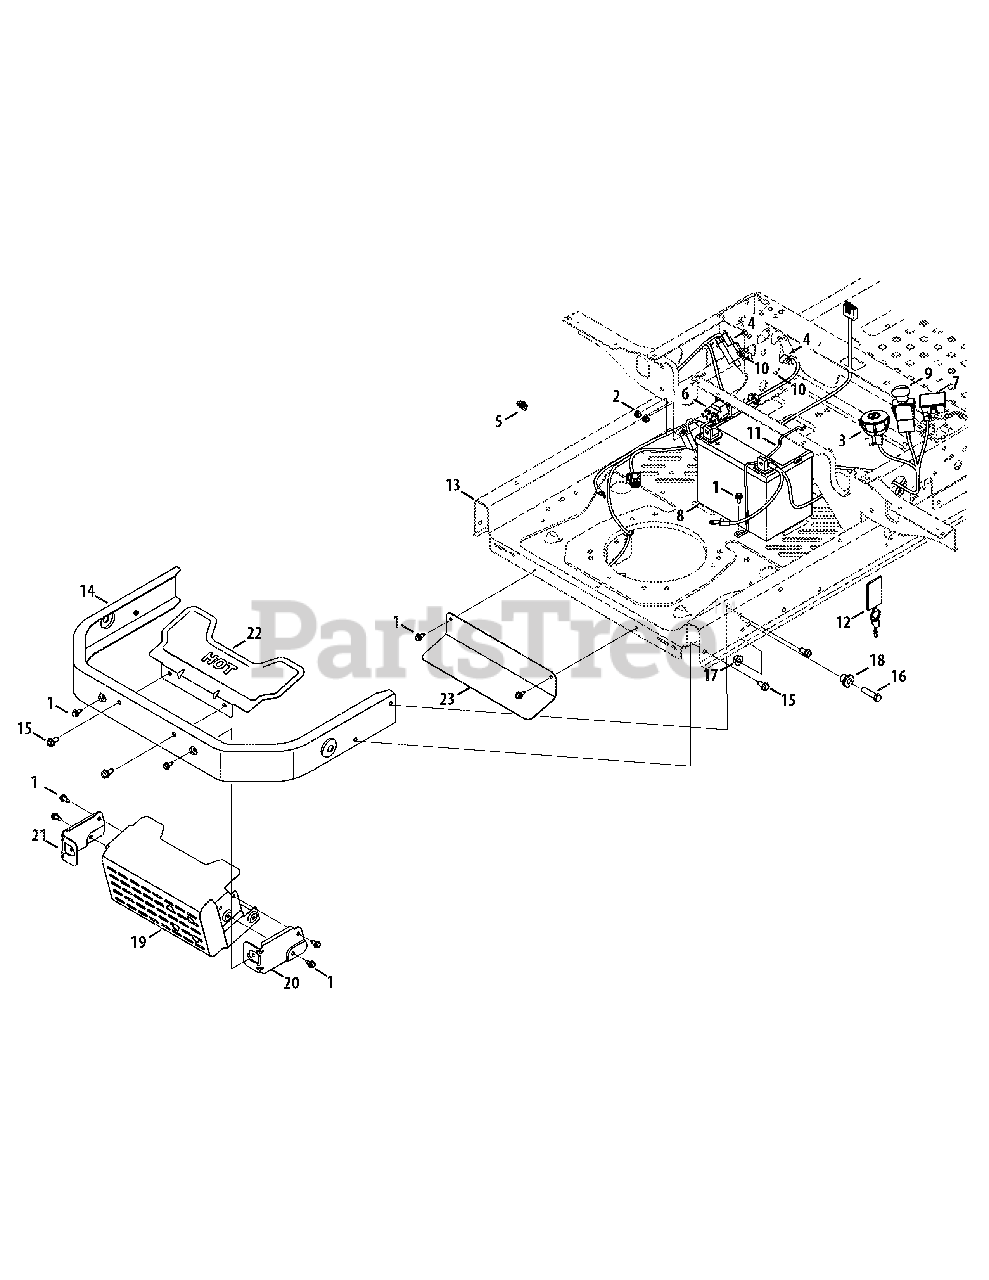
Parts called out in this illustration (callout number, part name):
1	Hex Washer Screw, 1/4-20 x .375
2	Flange Lock Nut, 1/4-20
3	Key Switch
4	Interlock Switch
5	Harness
6	Solenoid
7	Hour Meter/Service Minder
8	Battery
9	PTO Switch
10	Shoulder Screw
11	Battery Retainer
12	Key
13	Frame
14	Bumper
15	Hex Washer Screw, 5/16-18 x .750
16	Hex Screw, 3/8-16 x 1.25
17	Flange Lock Nut, 3/8-16
18	Shoulder Spacer, .38 x 1.0 x .70
19	Muffler Shield Assembly
20	RH Muffler Shield Mount Bracket
21	LH Muffler Shield Mount Bracket
22	Muffler Shield
23	Lower Heat Shield
